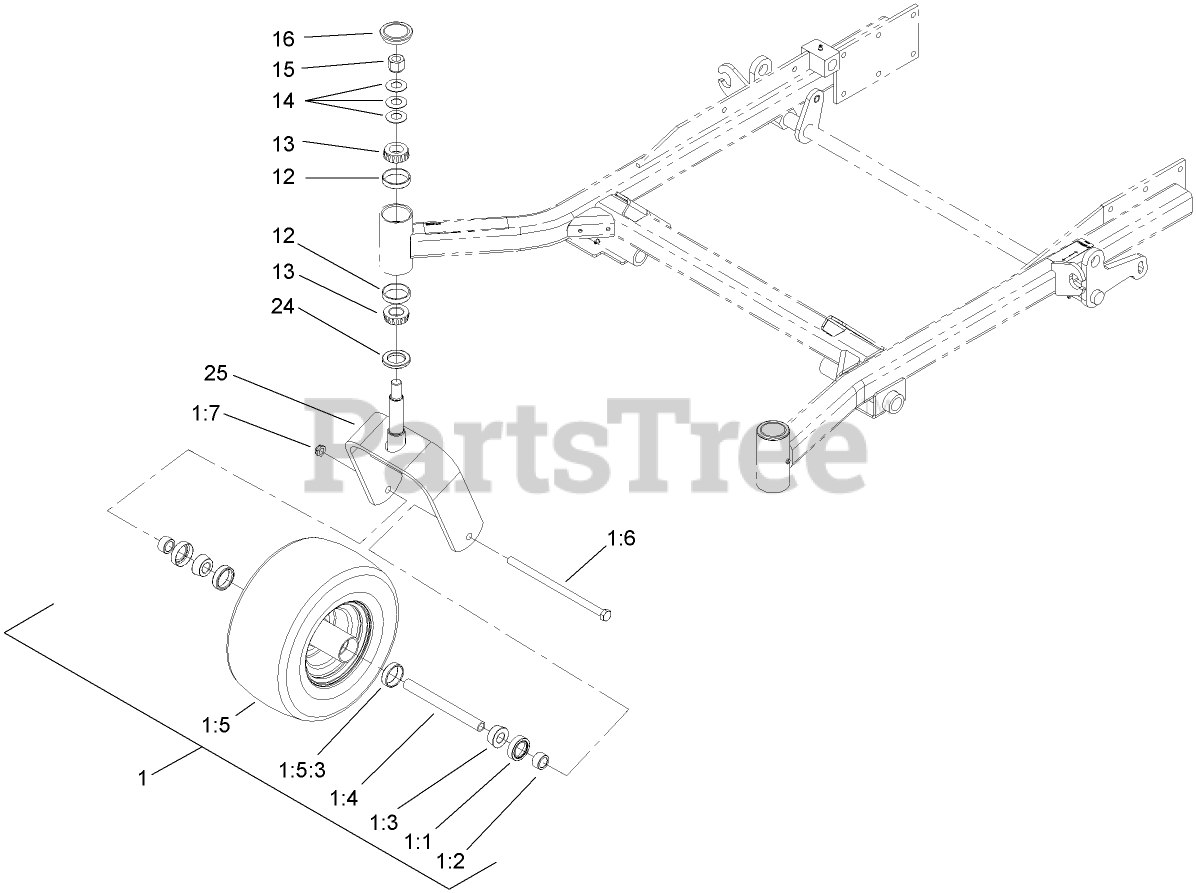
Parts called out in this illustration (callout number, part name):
1	CASTOR WHEEL ASM
1:1	SEAL-BEARING
1:2	SPACER-BEARING
1:3	BEARING-CONE, TAPER
1:4	SPACER-CASTER, FRONT
1:5	WHEEL AND TIRE ASM (SEMI-PNEUMATIC)
1:5:3	BEARING-CUP
1:6	SCREW-HH
1:7	NUT-LOCK, NI
12	BEARING-CUP, TAPERED
13	BEARING-CONE, TAPERED
14	WASHER-BELLVILLE
15	NUT-LOCK, NI
16	CAP-GREASE
24	SEAL-GREASE
25	CASTER
